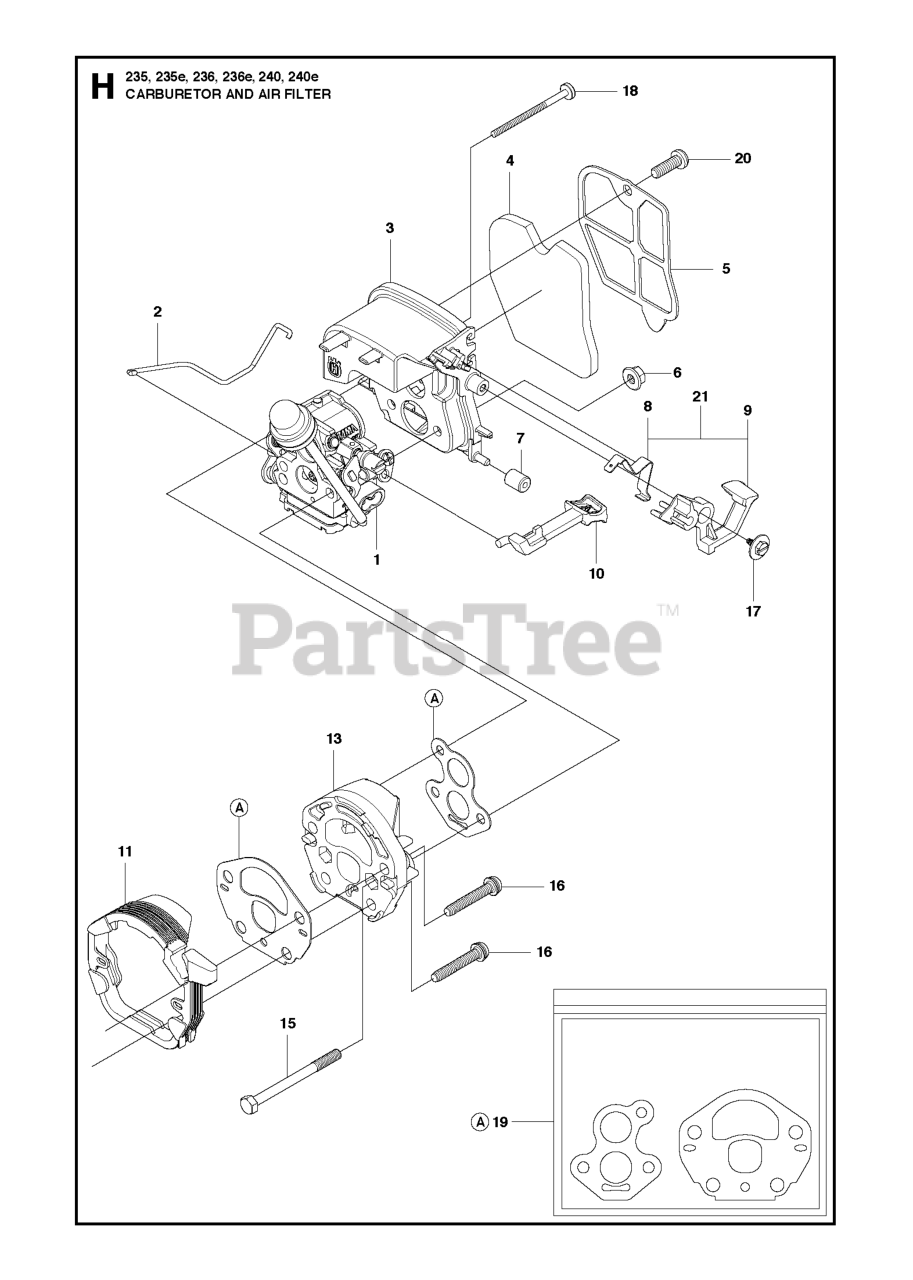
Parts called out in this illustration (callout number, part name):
1	CARBURETTOR 14MM AIR BORE, ANG
2	THROTTLE WIRE
2	TRIGGER & LOCKOUT KIT
3	AIR FILTER HOUSING BLACK
4	AIR FILTER
5	PLATE
7	ISOLATOR FILTER HOUSING
9	SWITCH LEVER
10	CHOKE KNOB
11	CARB ADAPTOR SEAL
13	ADAPTOR CARBURETOR
15	STUD CARBURETOR
17	SCREW
18	TOP STUD - CARBURETOR
19	GASKET KIT
20	SCREW FILTER PLATE
21	KIT SWITCH
